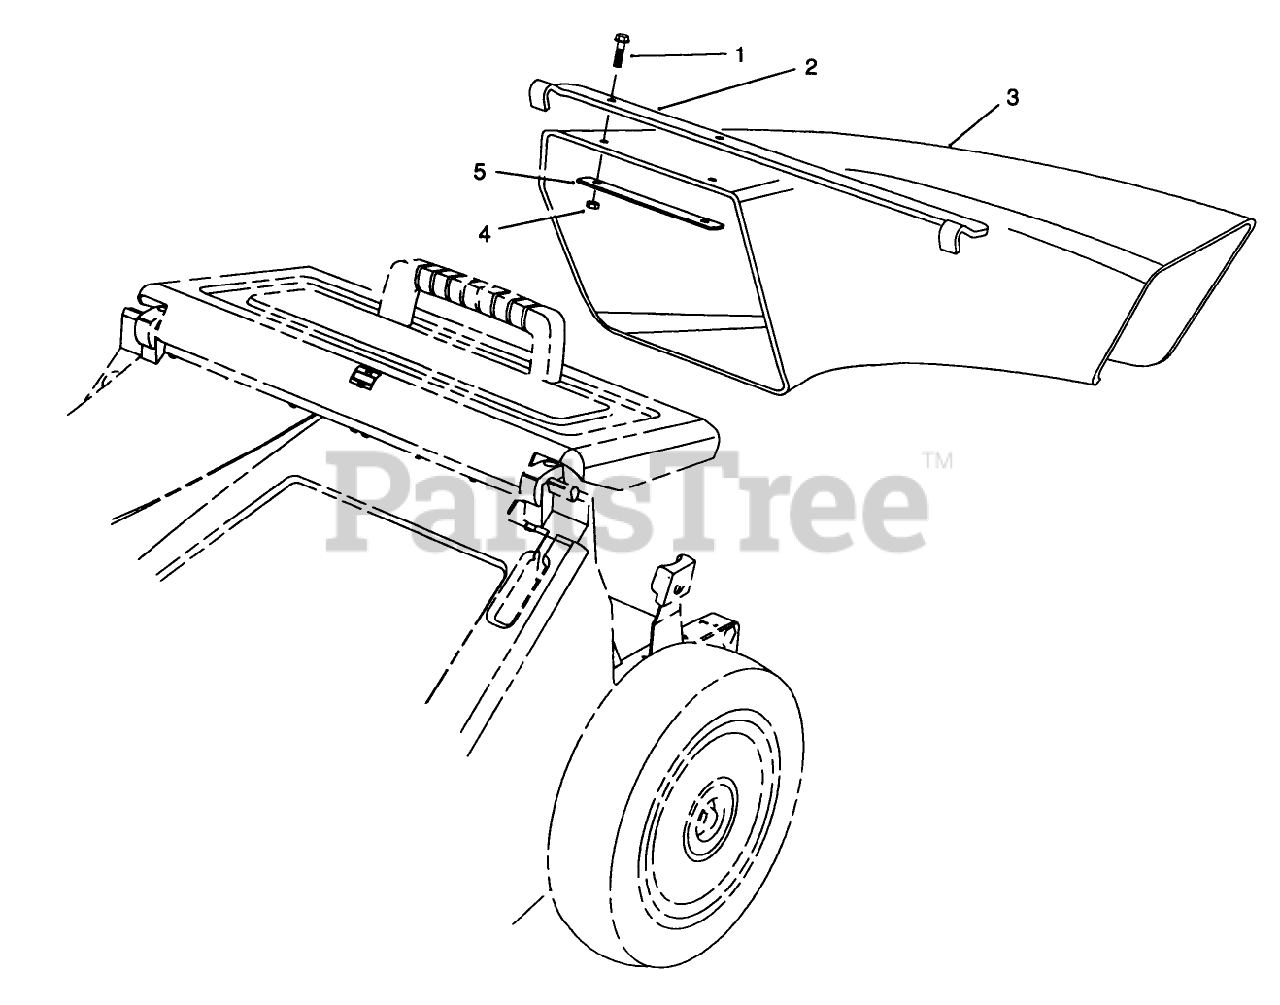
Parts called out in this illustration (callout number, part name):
1	SCREW-HWH
2	CHUTE HANGER BRACKET*
4	NUT-LOCK, NI
